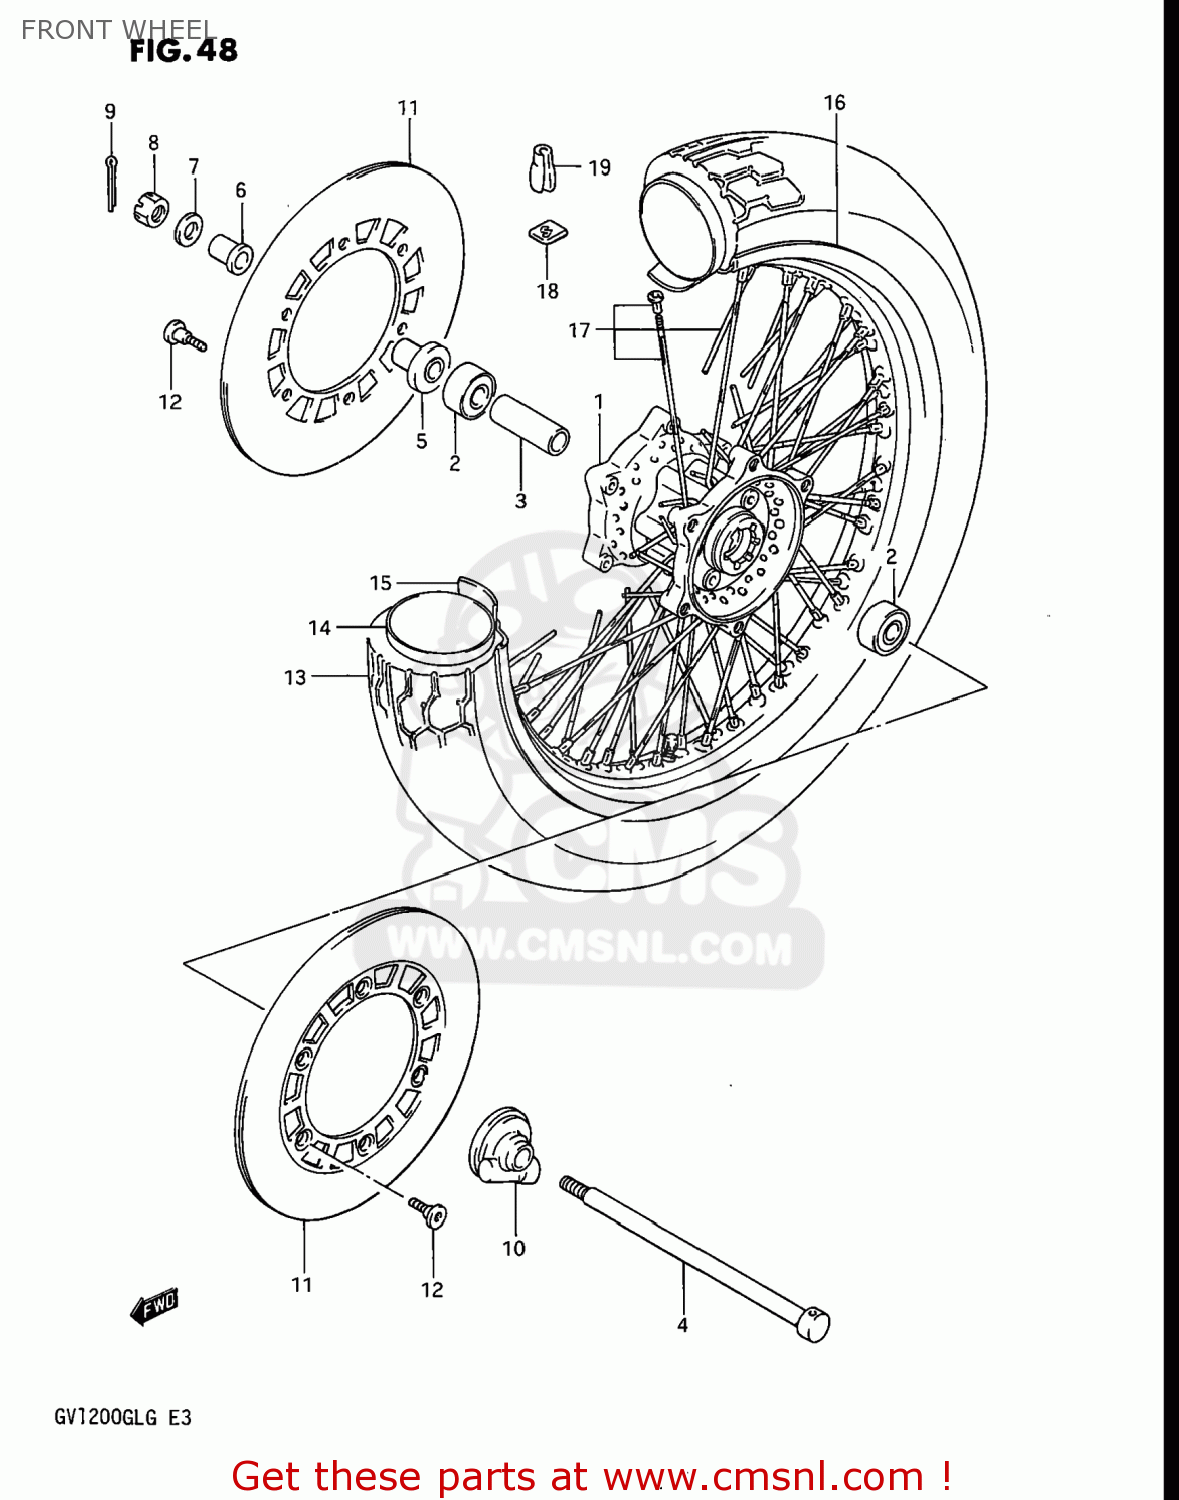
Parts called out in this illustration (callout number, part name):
1	HUB,FRONT
2	BEARING
3	SPACER
4	AXLE,FR
5	SPACER,FRONT AXLE,RIGHT
6	SPACER,FRONT AXLE,RIGHT
7	WASHER
8	NUT, REAR AXLE
9	COTTER PIN
10	BOX ASSY,SPEEDOMETER GEAR
11	DISC,BRAKE
12	BOLT(8X25.5)
13	TIRE 110/80-19
14	TUBE,INNER
15	PROTECTOR,WHL INR TUBE
16	RIM,FRONT WHEEL
17	SPOKE SET,FRONT
18	BALANCER,WHEEL NO.1
19	BALANCER,WHEEL
